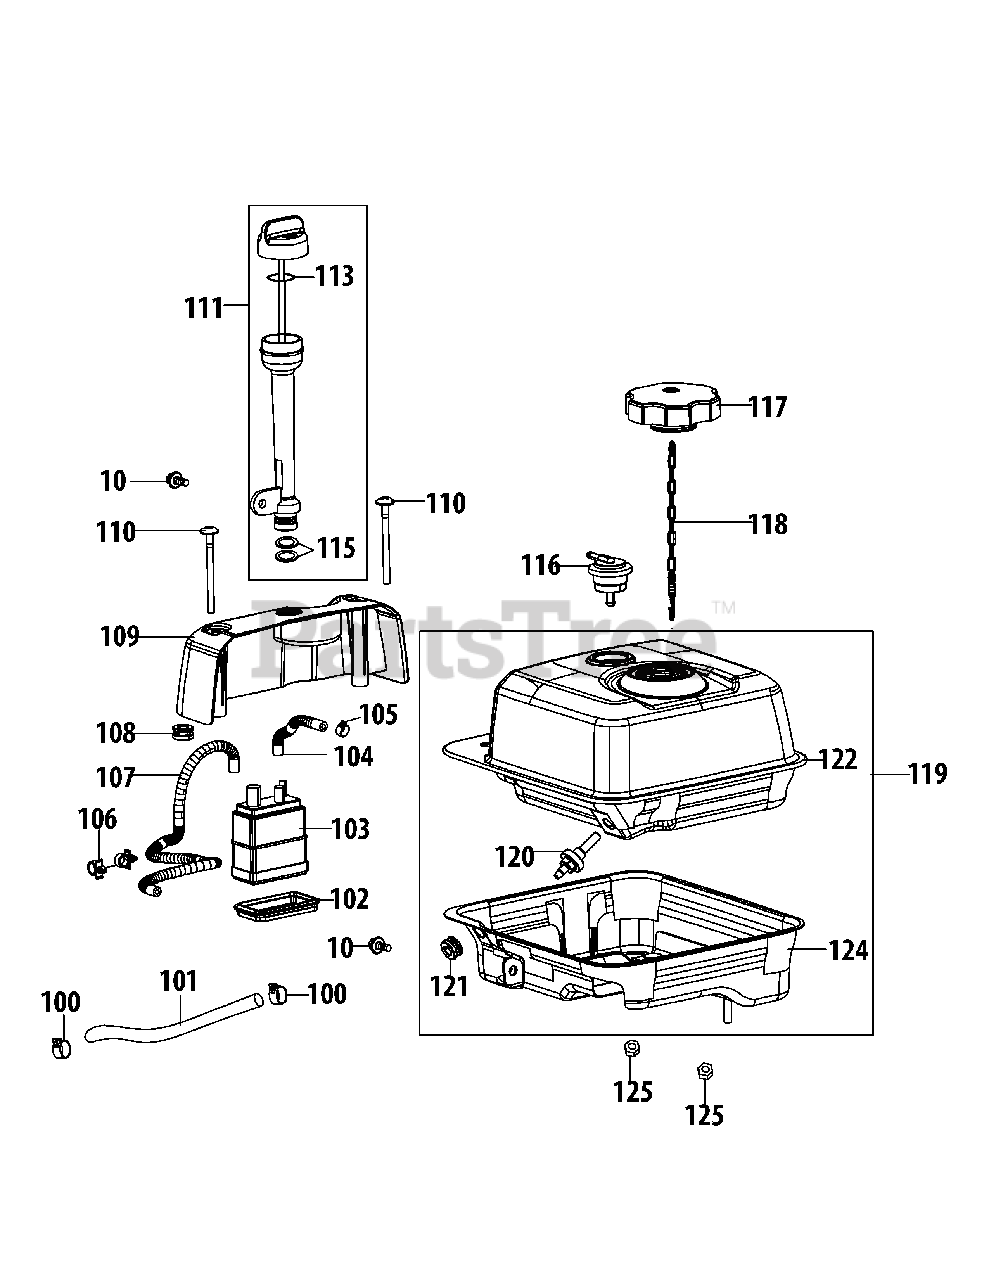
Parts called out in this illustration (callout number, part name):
10	Bolt M6×12
100	Clamp, Fuel Hose
101	Fuel Hose 6.3×12.5×123
102	Gasket, Carbon Canister
103	Carbon Canister
104	Fuel Hose 4×8×108
105	Clamp, Fuel Hose
106	Wire Clamp
107	Fuel Hose
108	Vibration Pad
109	Decoration Cover, Dipstick
110	Panel Bolt
111	Dipstick Assembly
113	O-Ring 21×2.77
115	O-Ring 15.5×1.5
116	Roll Over Valve
118	Fuel Cap Chain
119	Fuel Tank
120	Drain Pipe
121	Vibration Pad
122	Fuel Tank
124	Tank Base Combination
125	Flange Nut M6
